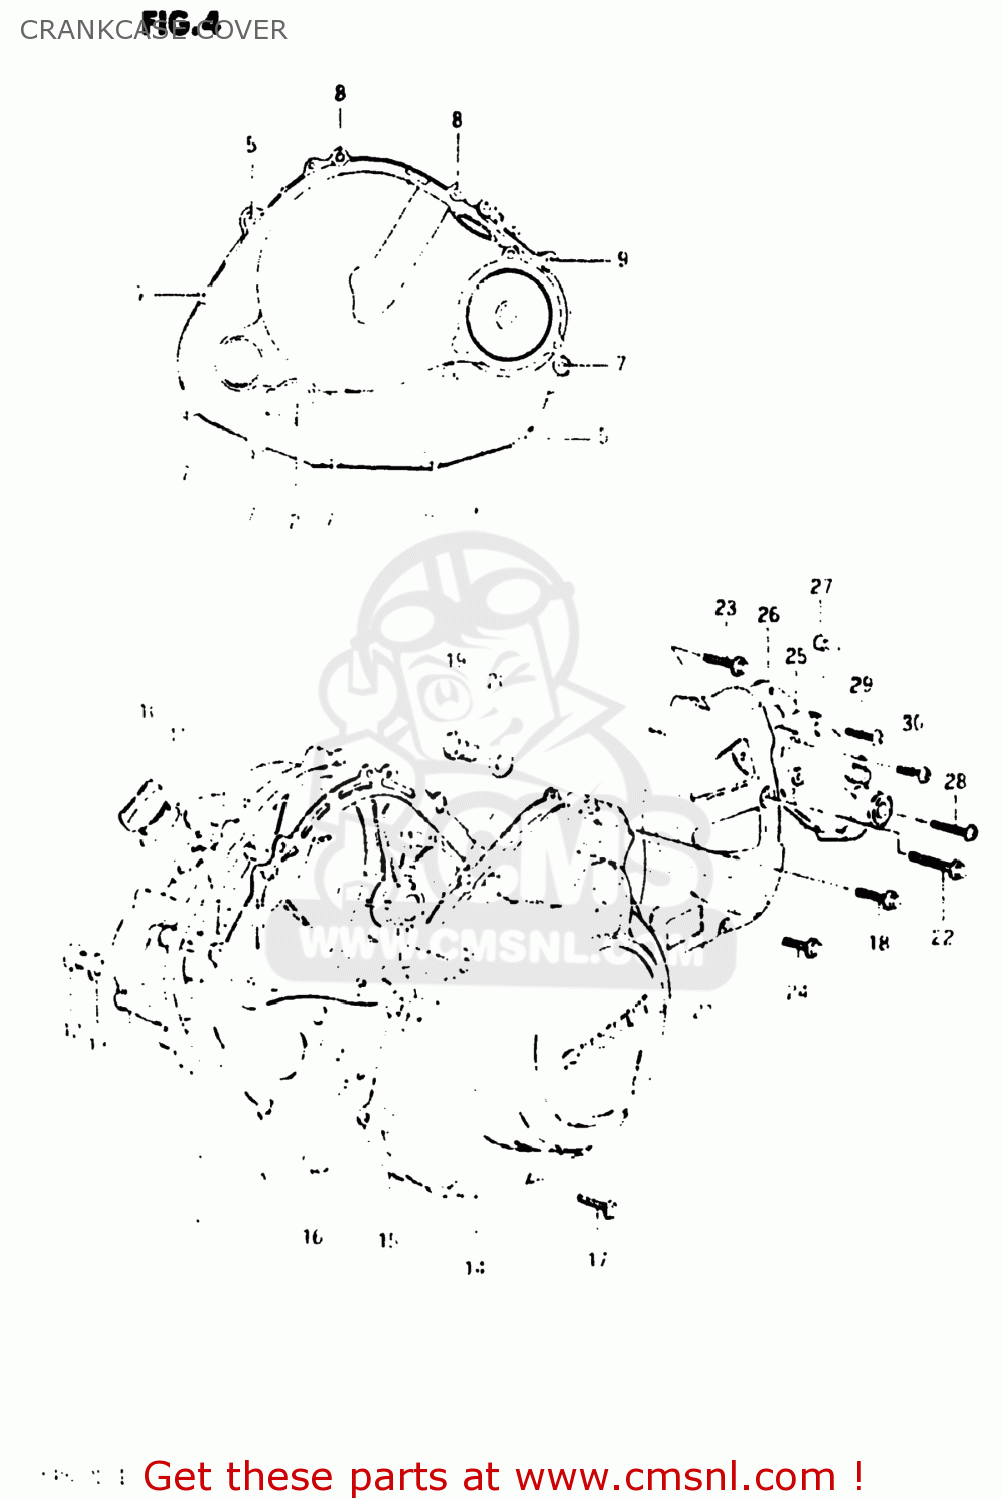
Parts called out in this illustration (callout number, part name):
1	COVER,CLUTCH
2	LENS,OIL LEVEL CHECK
3	GASKET,CLUTCH COVER (MCA)
4	PIN
5	BOLT 6X50
6	BOLT (6X40)
7	BOLT (6X35)
8	BOLT (6X25)
9	SCREW(6X25)
10	CAP
11	O RING(D:2.2,ID:32)
12	PLUG (14X12)
13	GASKET(14X19.2X2) (NAS)
14	COVER,MAGNETO
15	GASKET,MAGNETO COVER (MCA)
16	PIN
17	BOLT (6*30)
18	BOLT (6X25)
19	PLUG(12X9)
20	GASKET(12.1X16.2X3.7) (NAS)
21	COVER,ENGINE SPROCKET
22	BOLT (6X45)
23	BOLT (6*30)
24	BOLT 6X20
25	COVER,GEAR SHIFT
26	CUSHION,ENGINE SPROCKET
27	PIN
28	SCREW (6X35)
29	SCREW 6X30
30	SCREW
